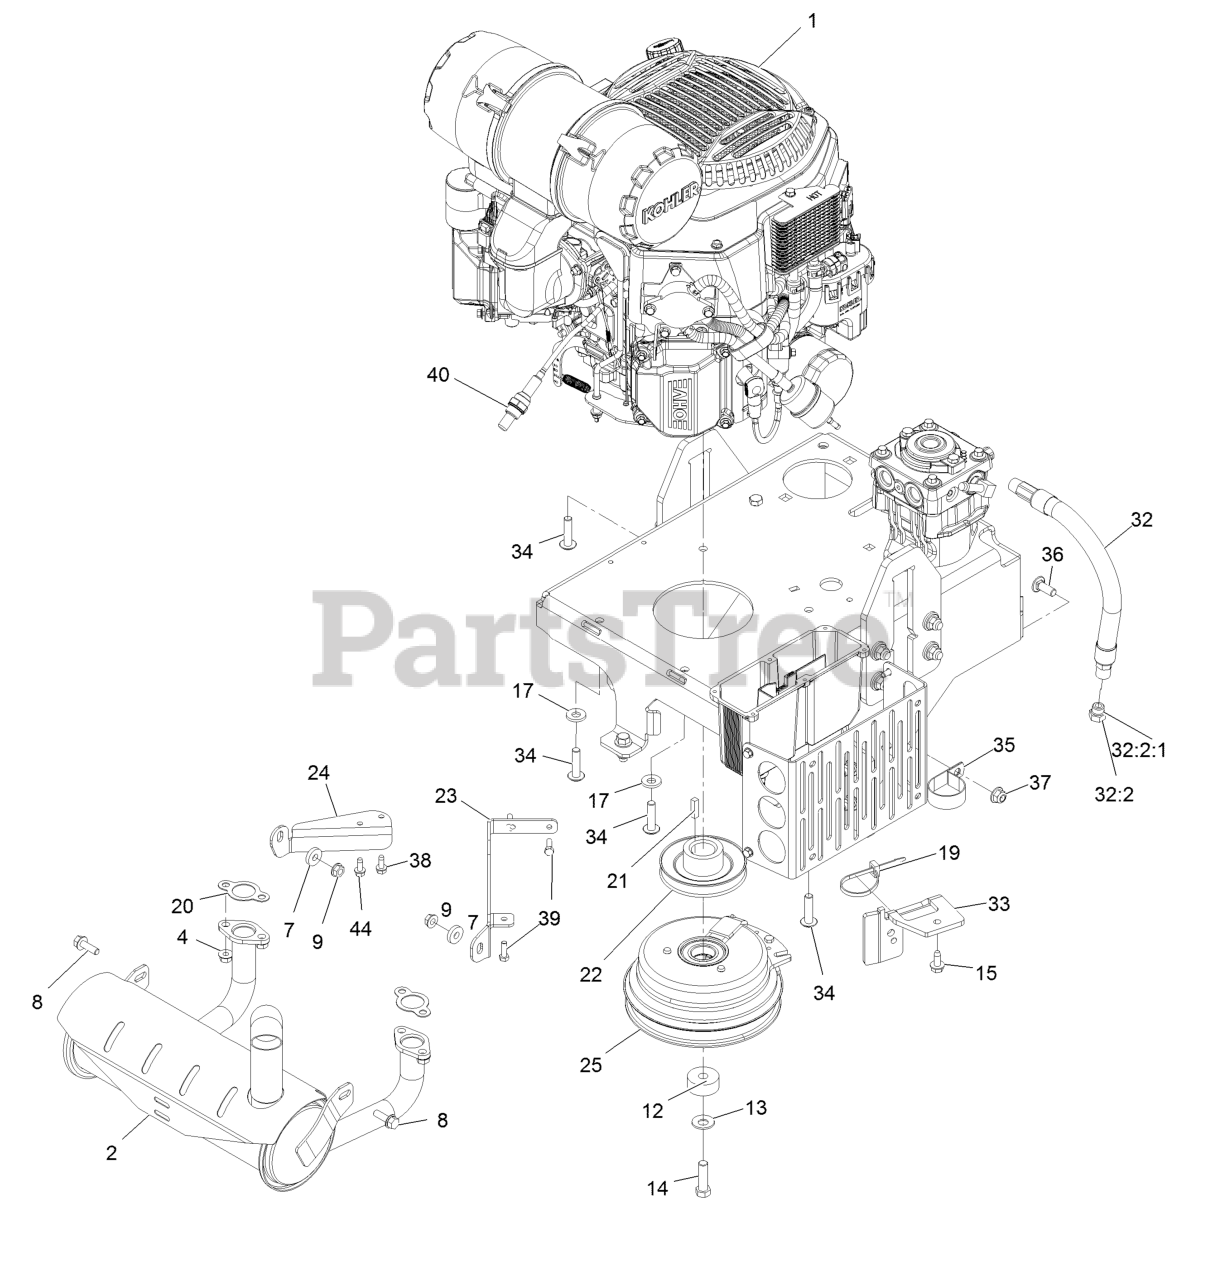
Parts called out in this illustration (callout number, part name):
2	Muffler-Kohler Efi
4	Nut-Flange
8	Screw-HH Flg 5/16-18 X 1
9	Nut-Hex 5/16-18 Side Lock
12	Keeper-Clutch
13	Washer-Spring Disc 7/16
14	Screw-HH 7/16-20 X 1 1/2
15	Screw-HWH 5/16-18 X 3/4 Tf
17	Washer-Spring Disc 3/8
19	Tie-Cable
20	Gasket-Exhaust
21	Key-Machine 1/4 X 1/4 X 1
23	Bracket-Muffler, LH
24	Bracket-Muffler, RH
25	Clutch-200 Ft-Lb, 1.125 Bore - No D Driv
32	Oil Drain Hose ASM
32:2	Plug-W/O-Ring
32:2:1	O-Ring
33	Bracket-Anchor, Clutch
34	Screw-BHTF
36	Bolt-Carriage 3/8-16 X 1
37	Nut-Nyloc 3/8-16 Flg
38	Screw-HWHTF
39	Screw-HH M6-1 X 20Mm W/Patch
40	Sensor-Oxygen
44	Screw-HWHTF
